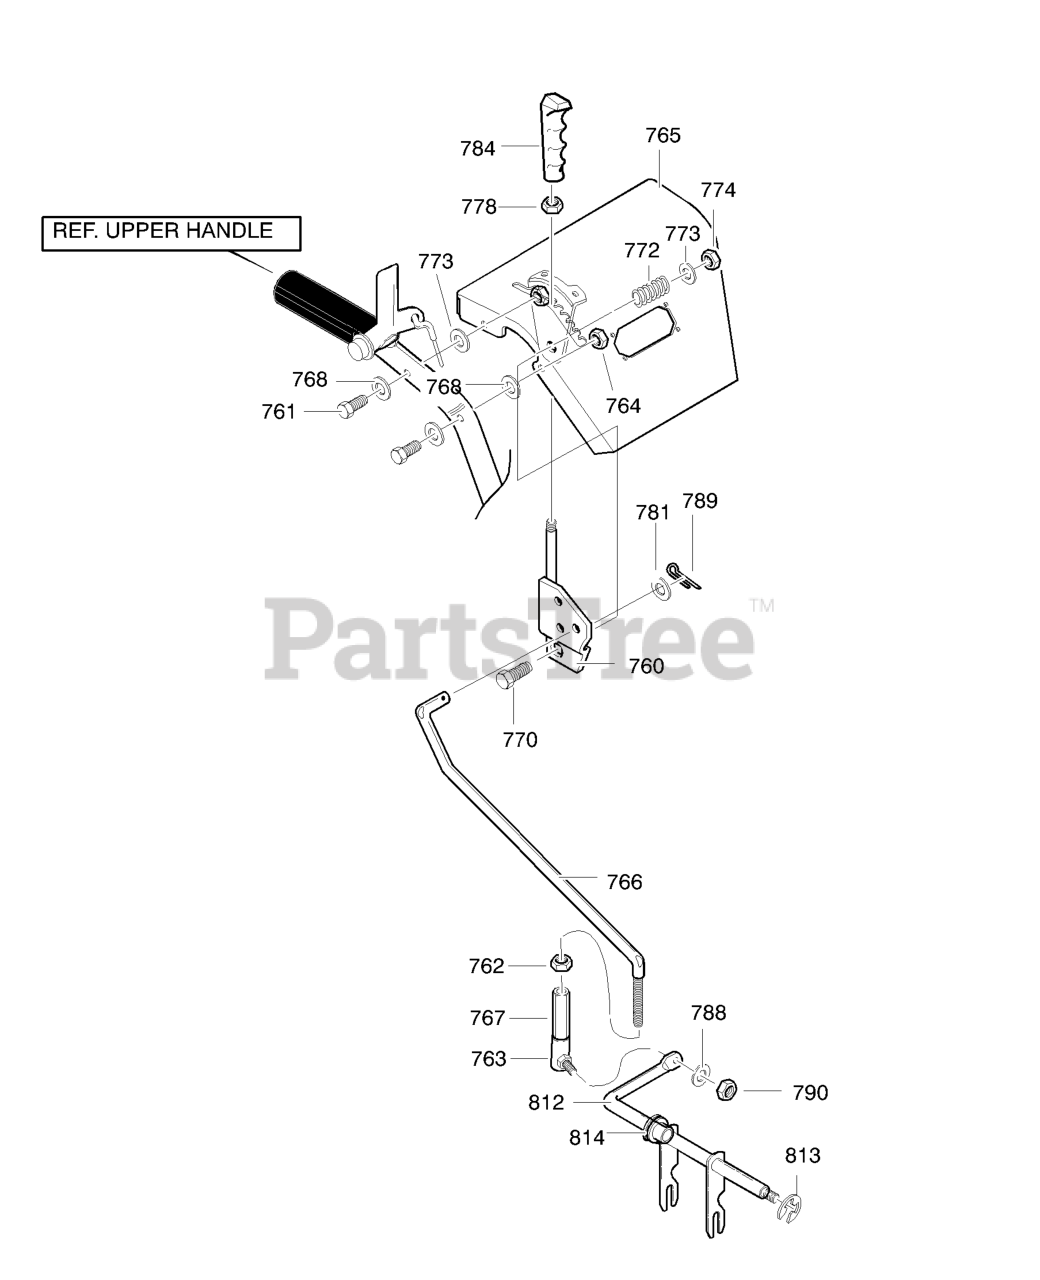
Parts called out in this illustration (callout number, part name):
760	HANDLE ASSY SPD CTRL
761	SCREW, 5/16-18 x 1.75
762	NUT, 5/16-24
763	JOINT, BALL
764	NUT, 5/16-18
765	ASSY. BAY LT
766	ROD, SPEED CONTROL
767	ADAPTER, ROD
768	WASHER
770	SCREW 3/8-16X2.00
773	FLATWASHER
774	NUT, 3/8-16
778	NUT, JAM 3/8-16
781	FLATWASHER
784	HANDLE, GRIP
788	FLATWASHER
789	PIN, COTTER
812	ROD, ASSY YOKE
813	RING, RETAINER
814	BEARING, FLANGE
